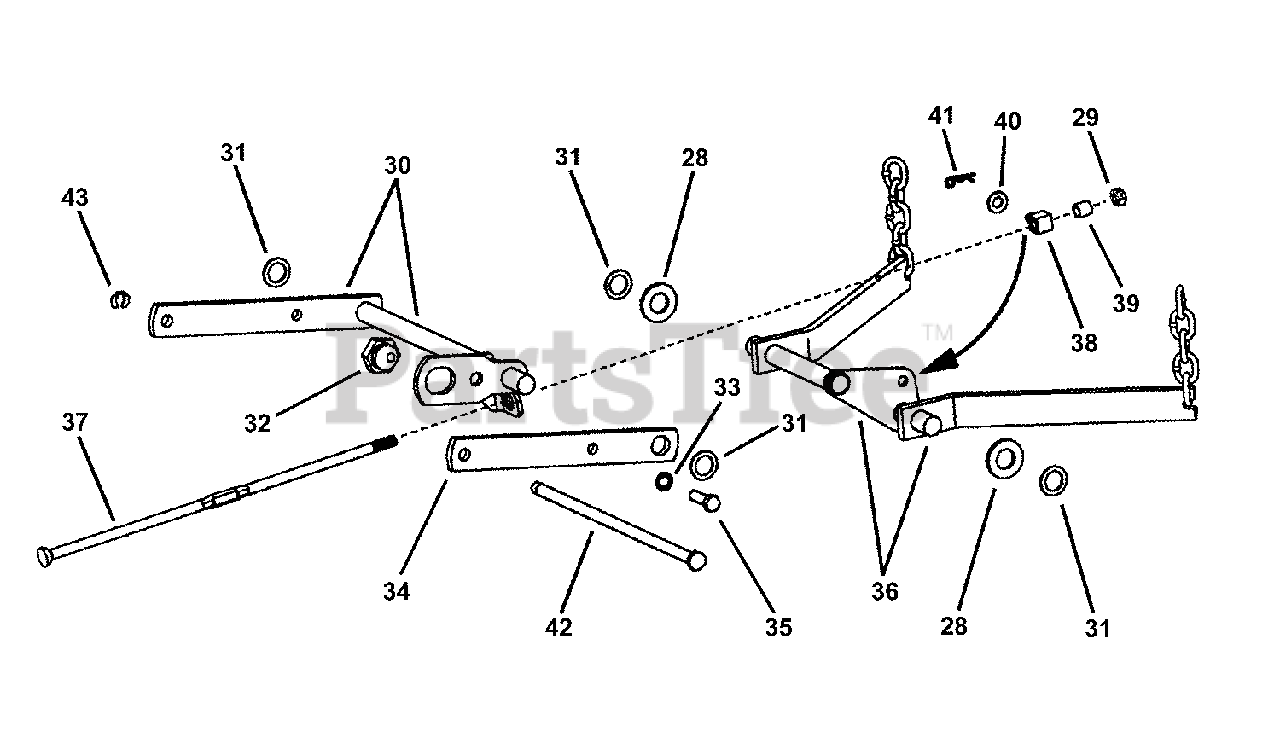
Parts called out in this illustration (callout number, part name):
28	WASHER, .781 x 1.5 x .132 Flat
29	NUT, 3/8-16 Hex Center Lock
30	WELDMENT, Lift Arm, Front
31	WASHER, 3/4" Flat
32	ECCENTRIC, Leveling
33	WASHER, 3/8" Internal Tooth Lock
34	LIFT ARM, Front
35	SCREW, 3/8-24 x 1-1/4" Hex Head Cap w/Nylon Patch, GR5
36	WELDMENT, Lift Arm, Rear
37	ROD, Cutter Deck Timing
38	SWIVEL, Brake Link- PM
39	SPACER, .391 I.D. x .531 long
40	WASHER, 3/8" SAE Flat
41	HAIR PIN, #13
42	ROD, Deck Support
43	RING, .438 External Retaining
